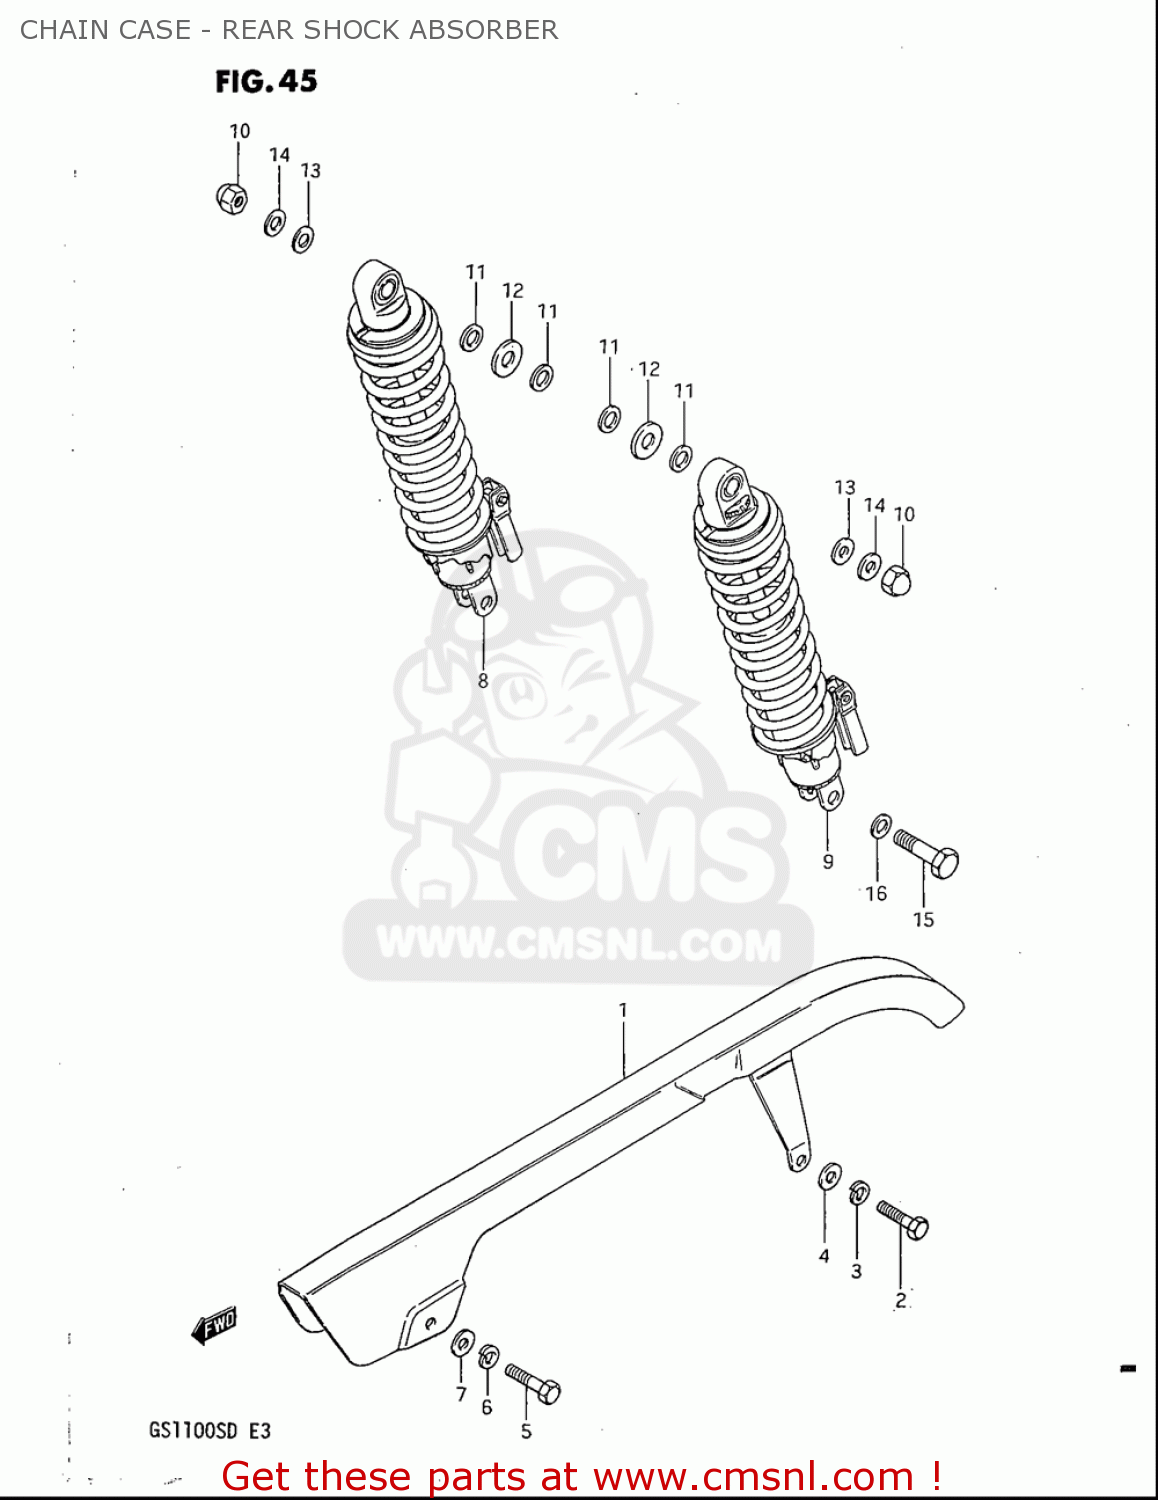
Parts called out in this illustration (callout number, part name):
1	CHAIN CASE
2	BOLT
3	WASHER,LOCK
4	WASHER
5	BOLT
6	WASHER,LOCK
7	WASHER(6.5X18X1.6)
10	NUT
11	WASHER
12	WASHER(12.5X24X3.2)
13	WASHER (10.5X24X2.3)
14	WASHER (10.5X25X3.2)
15	BOLT(10X36)
16	WASHER
